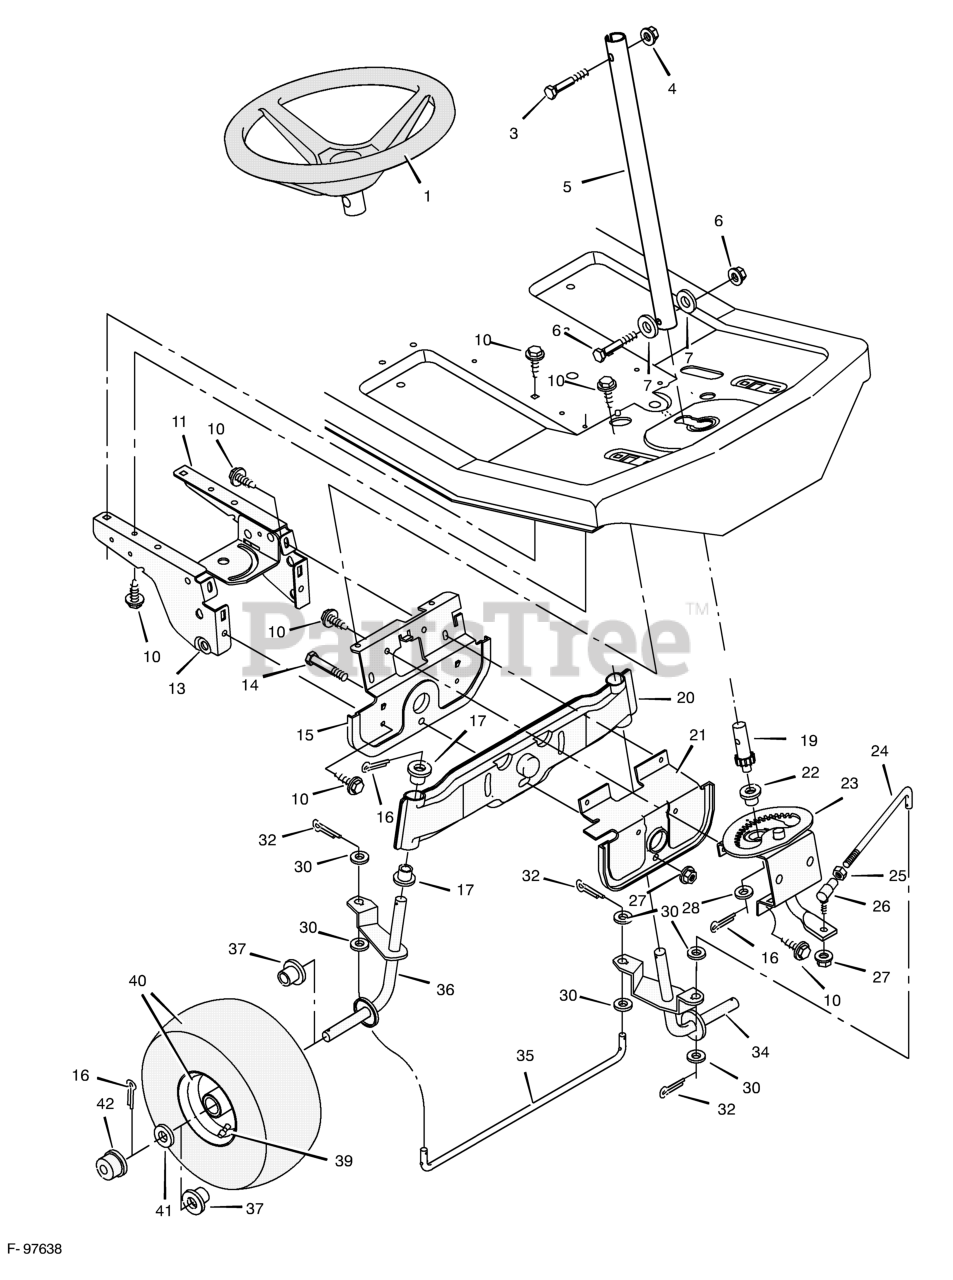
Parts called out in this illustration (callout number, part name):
1	Steering Wheel
3	Bolt, Hex
4	Locknut, Flange
5	Post, Steering
6	Nut, Hex
7	Washer
11	Plate, Left Suspension
13	Plate, Right Suspension
14	Bolt, Hex
15	Support, Front Axle
16	Pin, Cotter
17	Bearing, Spindle
19	Gear, Pinion
20	Axle Assembly, Front
21	Hanger Assembly, Front Axle
22	Bearing
23	Sector Assembly
24	Rod, Drag Link
25	Ball Joint, Steering
26	Nut, Hex
27	Locknut, Flange
28	Washer
30	Washer
32	Pin, Cotter
34	Spindle Assembly, Left
35	Rod, Tie
36	Spindle Assembly, Right
37	Bearing, Wheel
39	Valve Stem
40	Wheel & Tire Assembly
42	Cap, Hub
